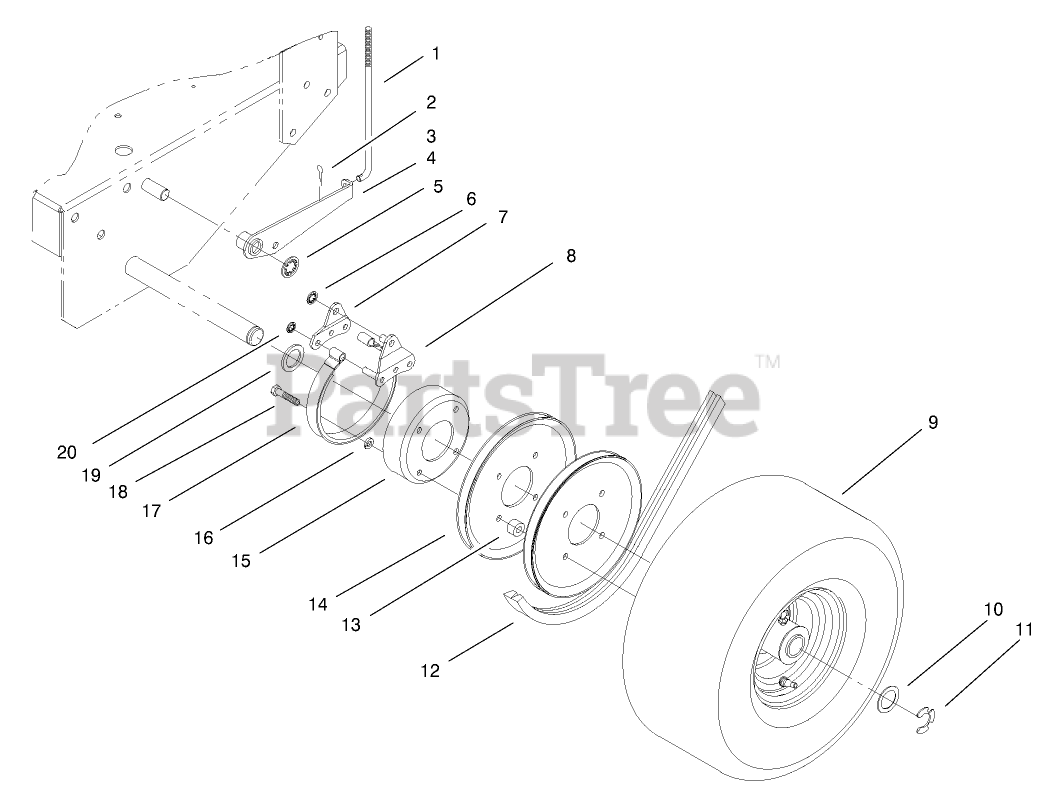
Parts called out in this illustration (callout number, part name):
1	ROD-BRAKE
2	PIN-COTTER
3	ARM-BRAKE, RH
4	ARM-BRAKE, LH
5	RING-RETAINING
6	RING-RETAINING, EXTERNAL
7	PLATE-LINK, BRAKE
8	LINK-BRAKE
9	Wheel/Tire Assembly
10	WASHER-THRUST
11	RING-RETAINING
12	V-BELT
13	SPACER-PULLEY
14	PULLEY-WHEEL
15	DRUM-BRAKE
16	WASHER-LOCK
17	BAND-BRAKE
18	SCREW-HH
19	WASHER-WHEEL
20	RING-RETAINING
